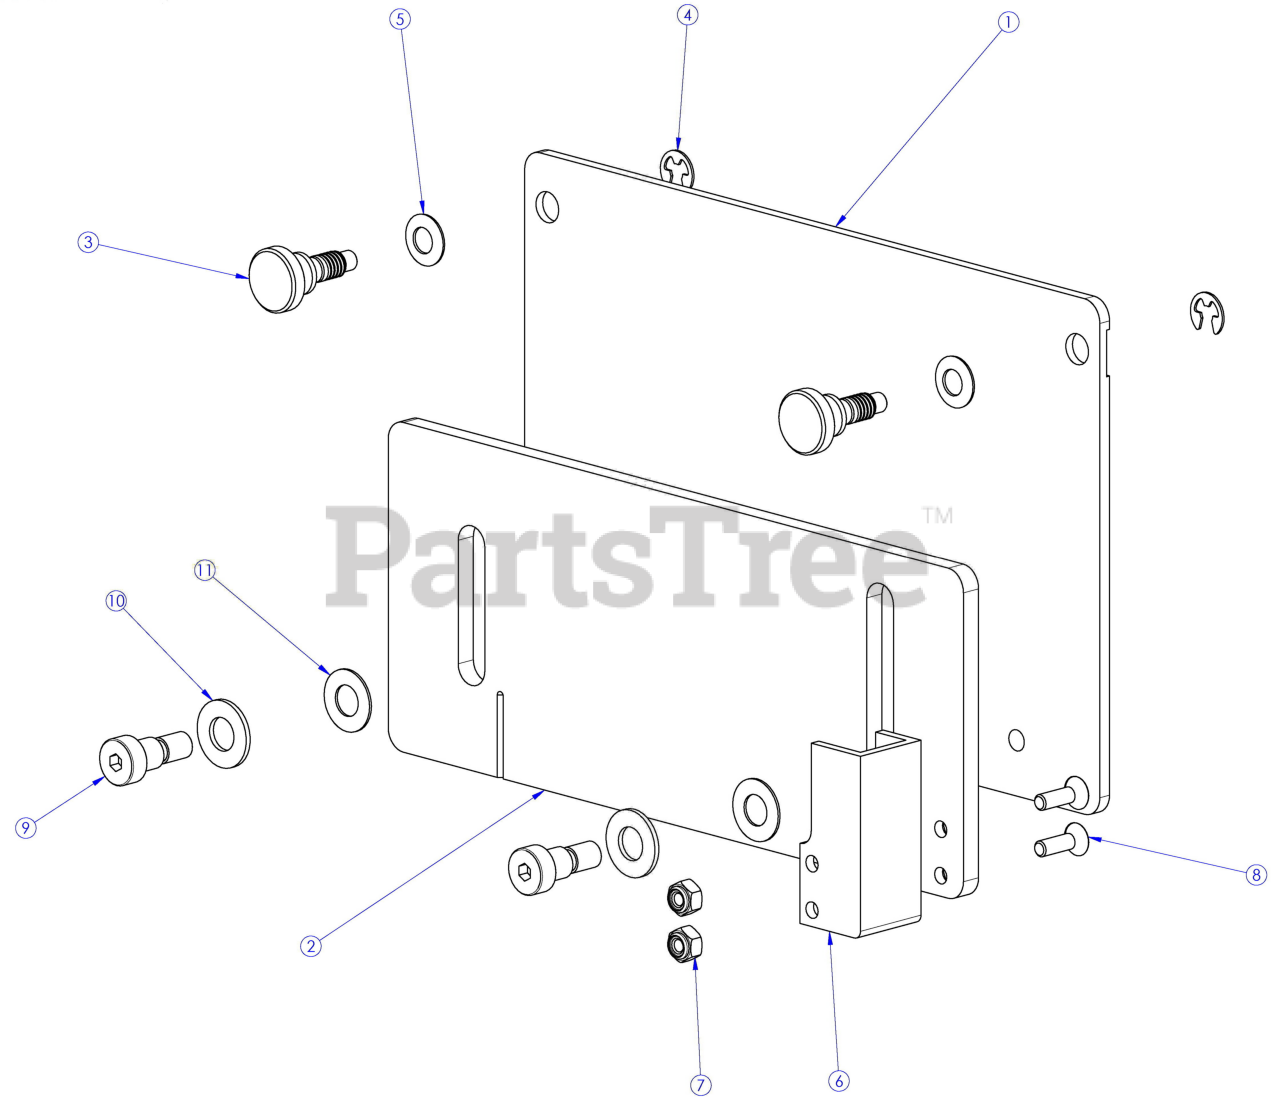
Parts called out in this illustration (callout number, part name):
2	Cover, Outer Lexan
3	Knob, Bb Cover
4	E-Clip, 1/4"
5	Washer, Bellevelle
6	Channel, Outer Diverter
7	Nut, Nyloc, #10-24 Cad
8	Fhs, 10-24 X 5/8 S.S.
9	Shsb, 3/8 X 3/8
10	Washer, 3/8" Flat
11	Washer, 3/8" Delrin
